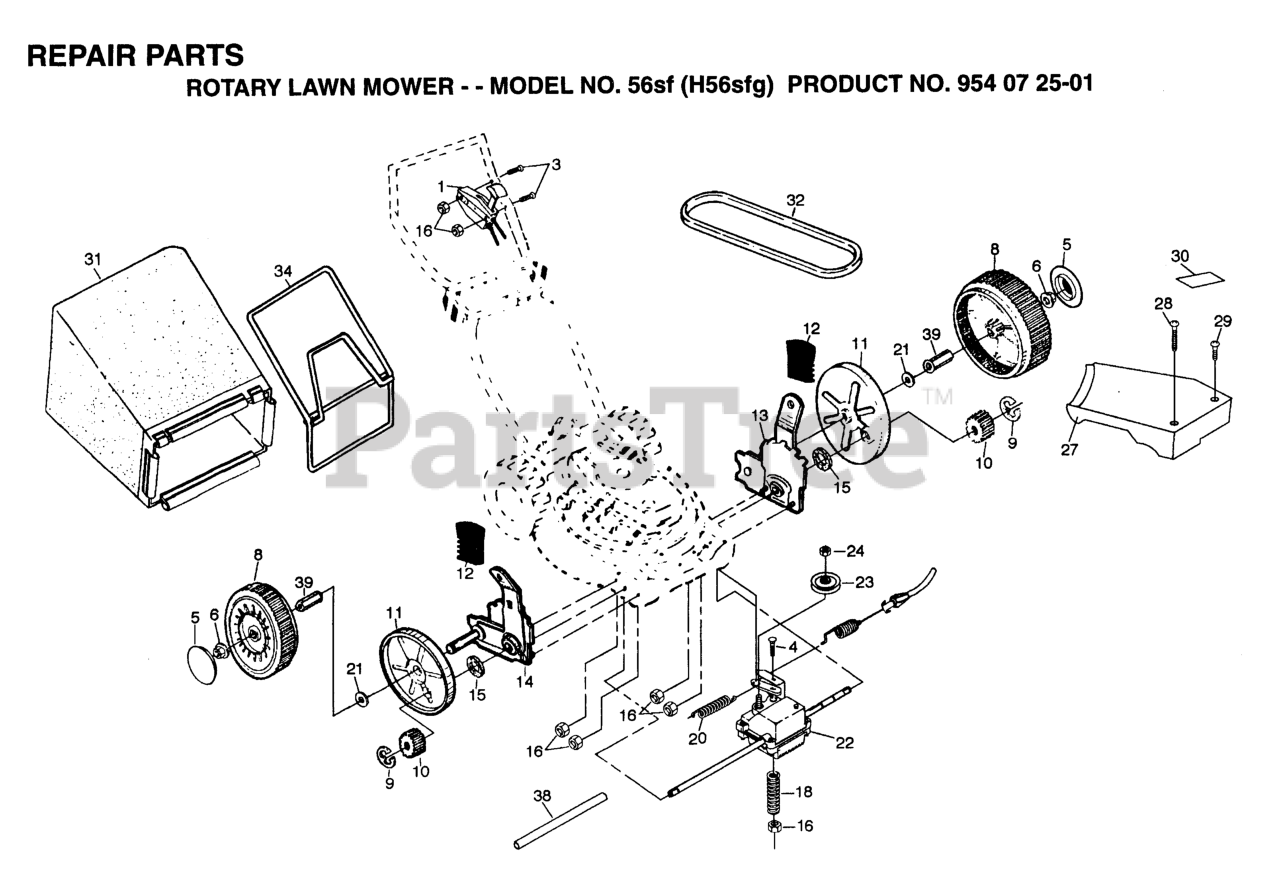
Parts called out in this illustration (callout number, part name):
1	DRIVE CONTROL
3	SCREW 1/4-20 X 2.12
6	NUT
8	DRIVE WHEEL
9	E-RING 7/16 RE
10	PINION GEAR
11	DUST SHROUD PM
12	SELECTOR KNOB
13	BRACKET-LH
14	BRACKET
16	NUT
18	SPRING.EXTENSION
21	WASHER FLUT
22	GEAR CASE ASMBLY
23	PULLEY
24	FLANGED LOCKNUT 3/8-16 ZINC
27	DRIVE COVER-GRAY
29	SCREW
30	DECAL (DRIVE COVER)
32	BELT DRIVE
34	CATCHER.FRAME.WALK
35	GRASS BAG
38	DRV SHAFT TUBE PM
39	BUSHING PM
